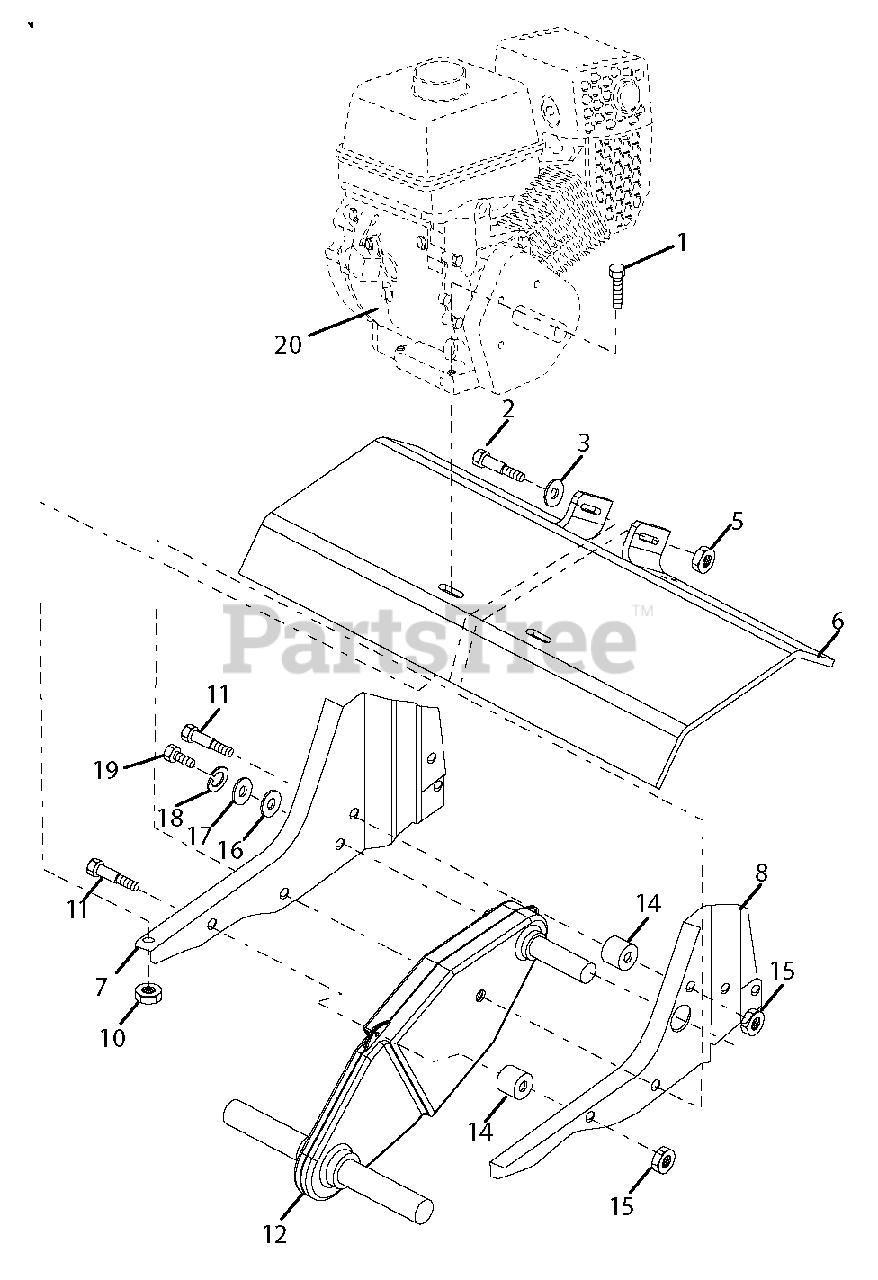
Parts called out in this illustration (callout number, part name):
1	BOLT
5	NUT LOCK FLG 3/8-16 UNC
6	SHIELD.TINE.24.YELLOW.TILLER
7	BRACKET.ENGINE.RH.TILLER.BLACK
8	BRACKET.ENGINE.TILLER.BLACK
10	LOCKNUT-FLANGE 5/16-18
11	BOLT, HEX HEAD 5/16-18 X 2.5
12	TRANSMISSION.ASM.W/1".D-SHAFT
14	SPACER.SPLIT.327 X 1.00
15	NUT.LOCK.5/16-18
18	LOCKWASHER
20	ENGINE.LCT.208CC.14650124P
